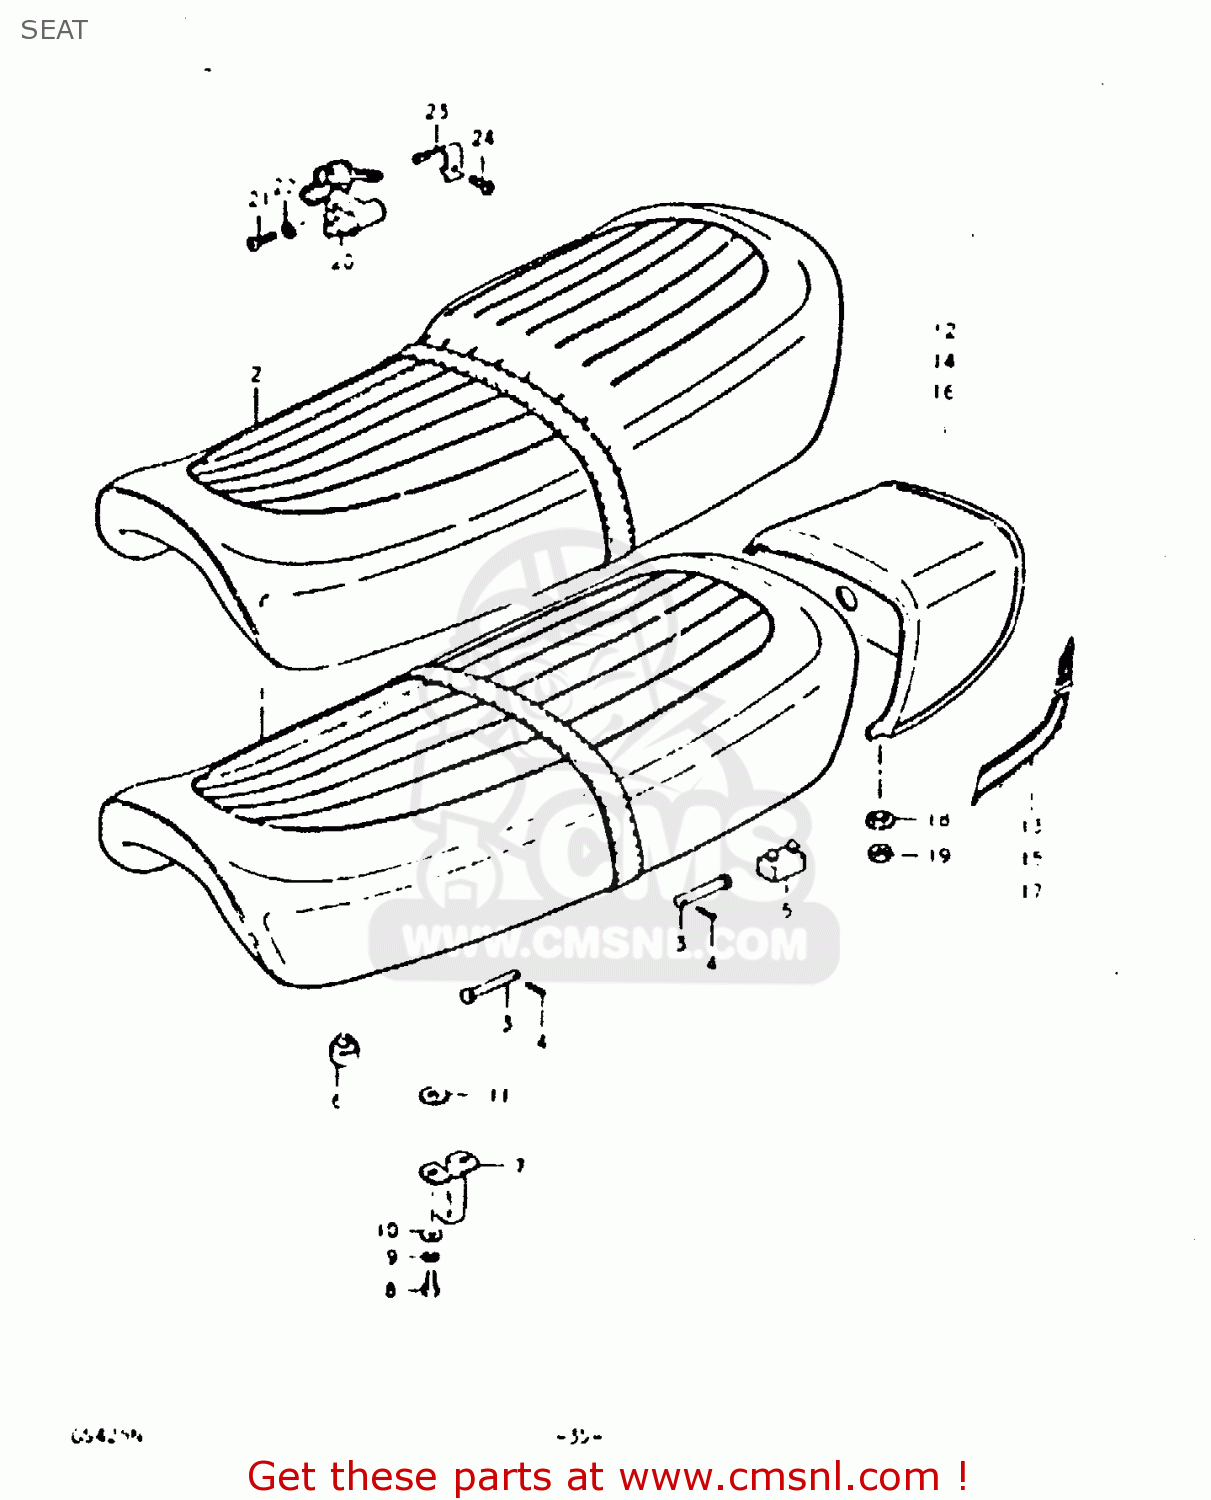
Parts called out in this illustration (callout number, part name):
1	SEAT ASSEMBLY
2	SEAT ASSEMBLY
3	PIN
4	PIN
5	CUSHION
6	CUSHION(11.5X22X20)
7	STRIKER,SEAT LOCK
8	BOLT
9	LOCK WASHER
10	WASHER
11	WASHER(8.5X18X1)
12	COVER,SEAT TAIL
13	TAPE SET
14	COVER, SEAT TAIL
15	TAPE SET
16	COVER,SEAT TAIL
17	TAPE SET
18	WASHER
19	NUT 6MM
20	LOCK ASSY,SEAT
21	SCREW
22	LOCK WASHER
23	SPRING,HELMET HOLDER
24	BOLT 5X16
